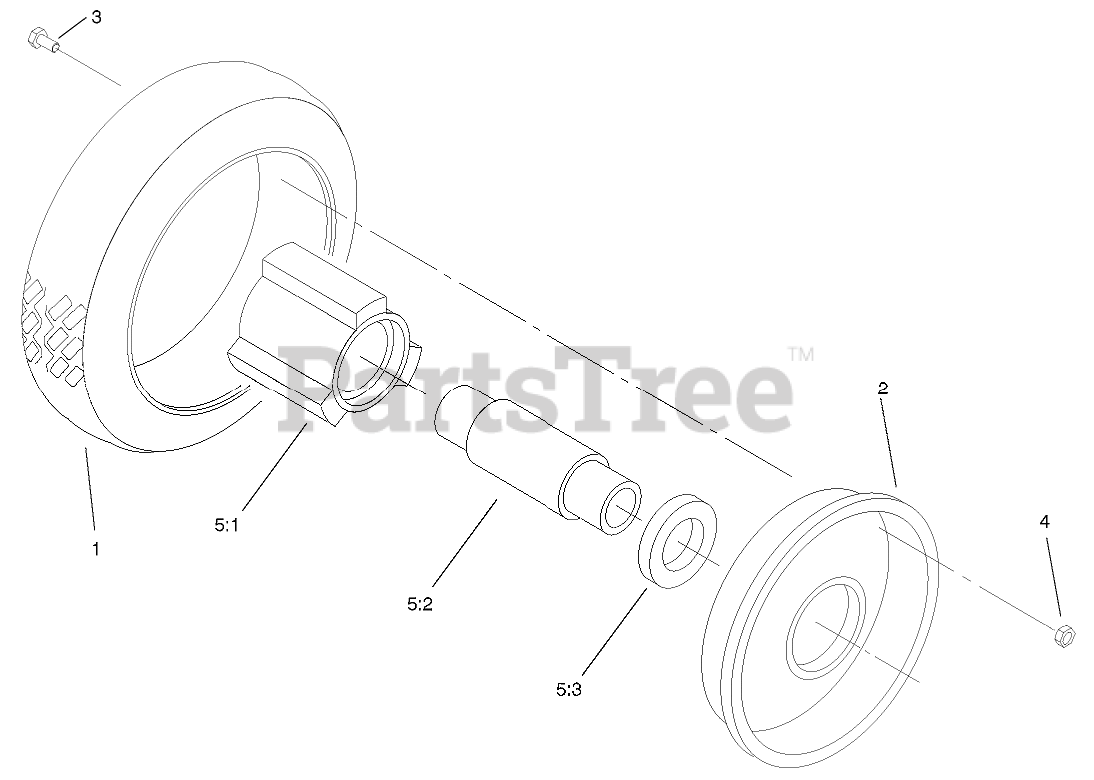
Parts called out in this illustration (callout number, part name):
2	PLATE-WHEEL, HALF
3	SCREW-HH
4	NUT-LOCK, NI
5	Hub and Bearing ASM
5:1	HUB-BEARING
5:2	SPACER-BEARING
5:3	BEARING-WHEEL
